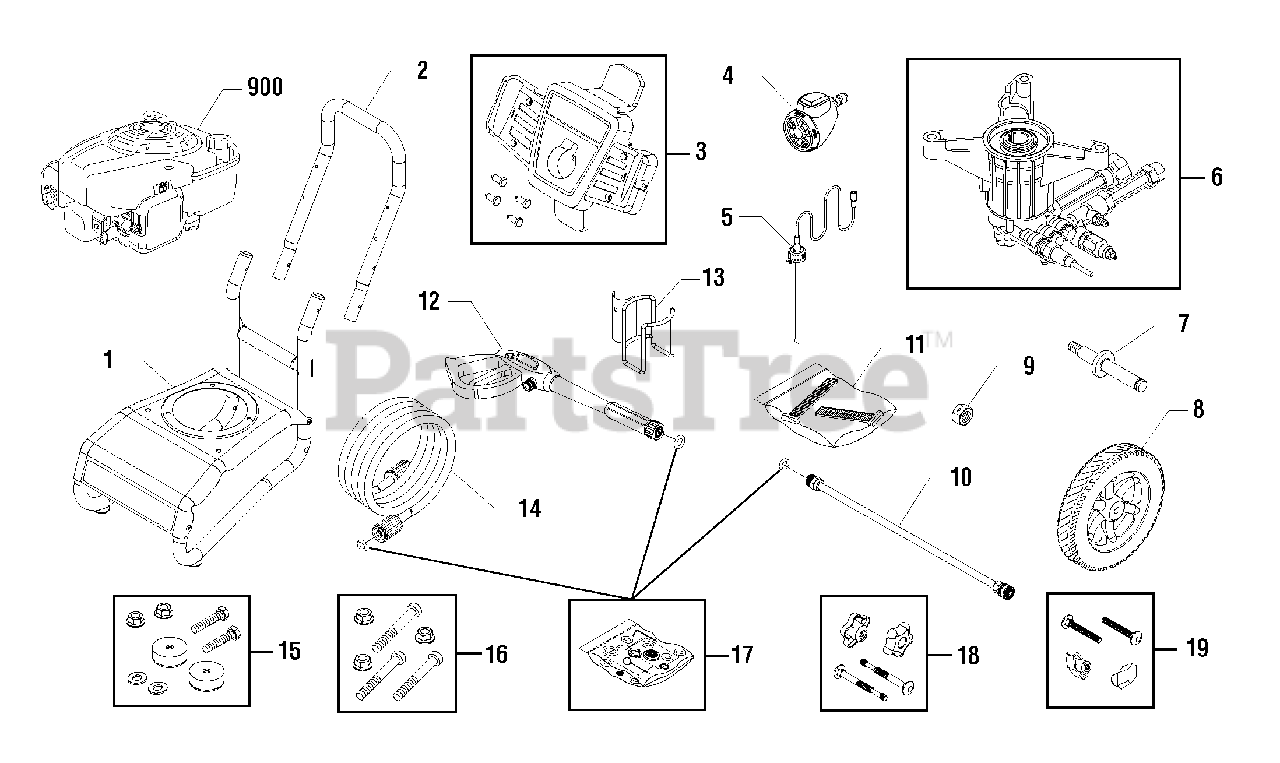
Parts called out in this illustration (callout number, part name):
12	GUN
14	HOSE
15	MOUNT-VIBRATION
16	KIT-HARDWARE PUMP MOUNTING
900	** ENGINE
